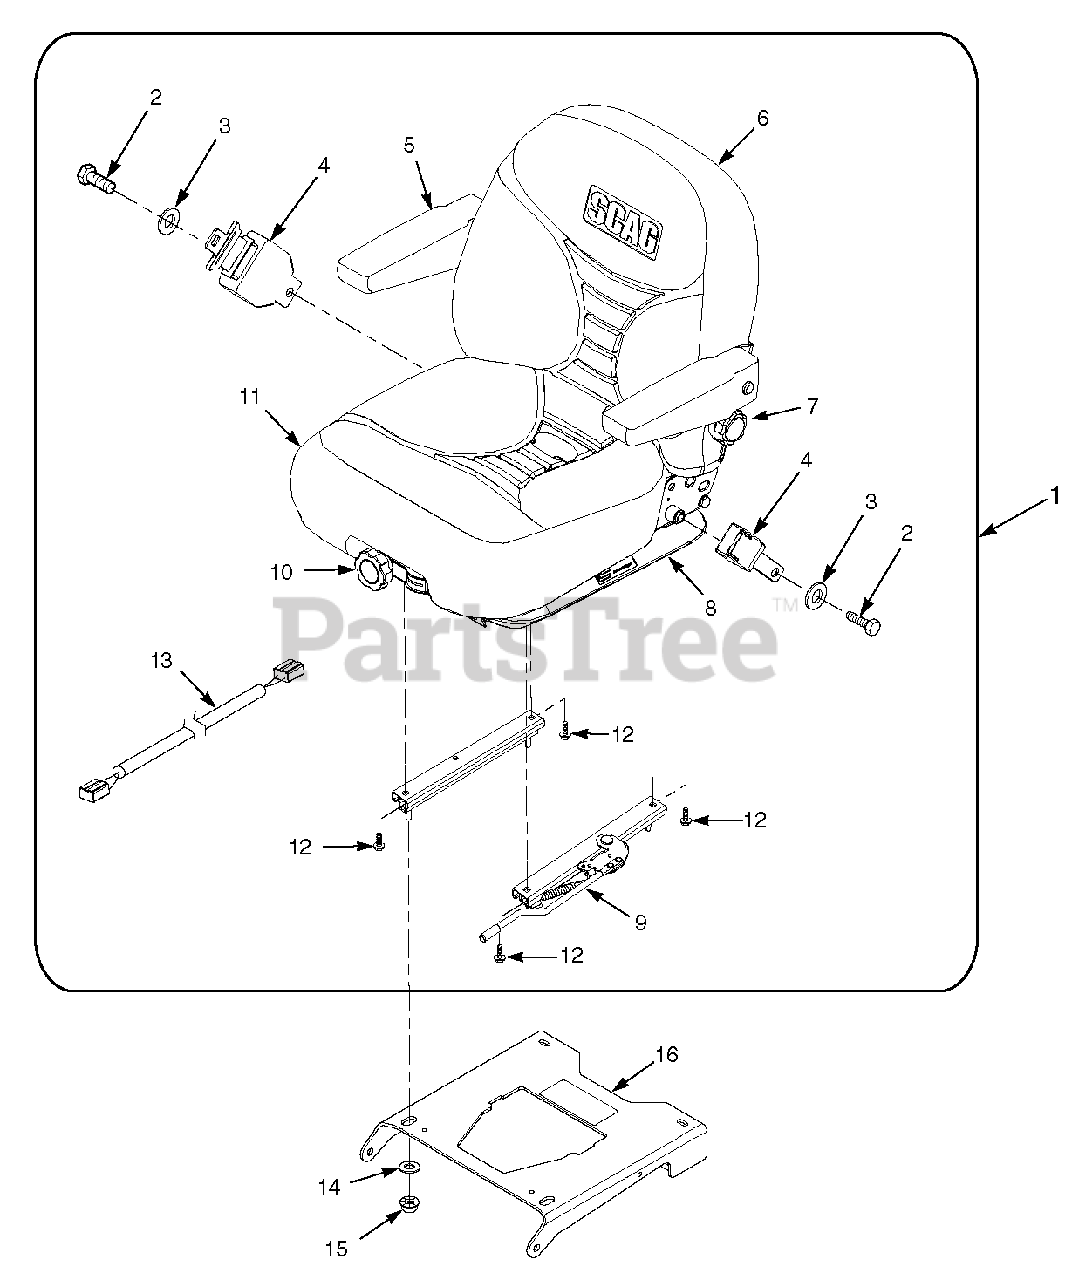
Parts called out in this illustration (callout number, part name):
1	Suspension Seat Assembly w/seat belt
2	Bolt, Hex Head 7/16-20 x 1"
3	Flatwasher, 7/16-.500 x 1.25 x .083
4	Retractable Seat Belt
5	Armrest Only
6	Back Cushion Kit
7	Lumbar Kit
8	Shock Absorber Kit
9	Seat Adjustment, Track Set
10	Weight Adjustment Kit
11	Seat Cushion Kit Seat Drain Kit
12	Bolt, Hex Head 5/16-18 x 1-3/4"
13	Wire Harness Adapter
14	Flatwasher, 3/8-.391 x .938 x .105
15	Nut, Serrated Flange 5/16-18
16	Seat Plate Weldment w/Decal
